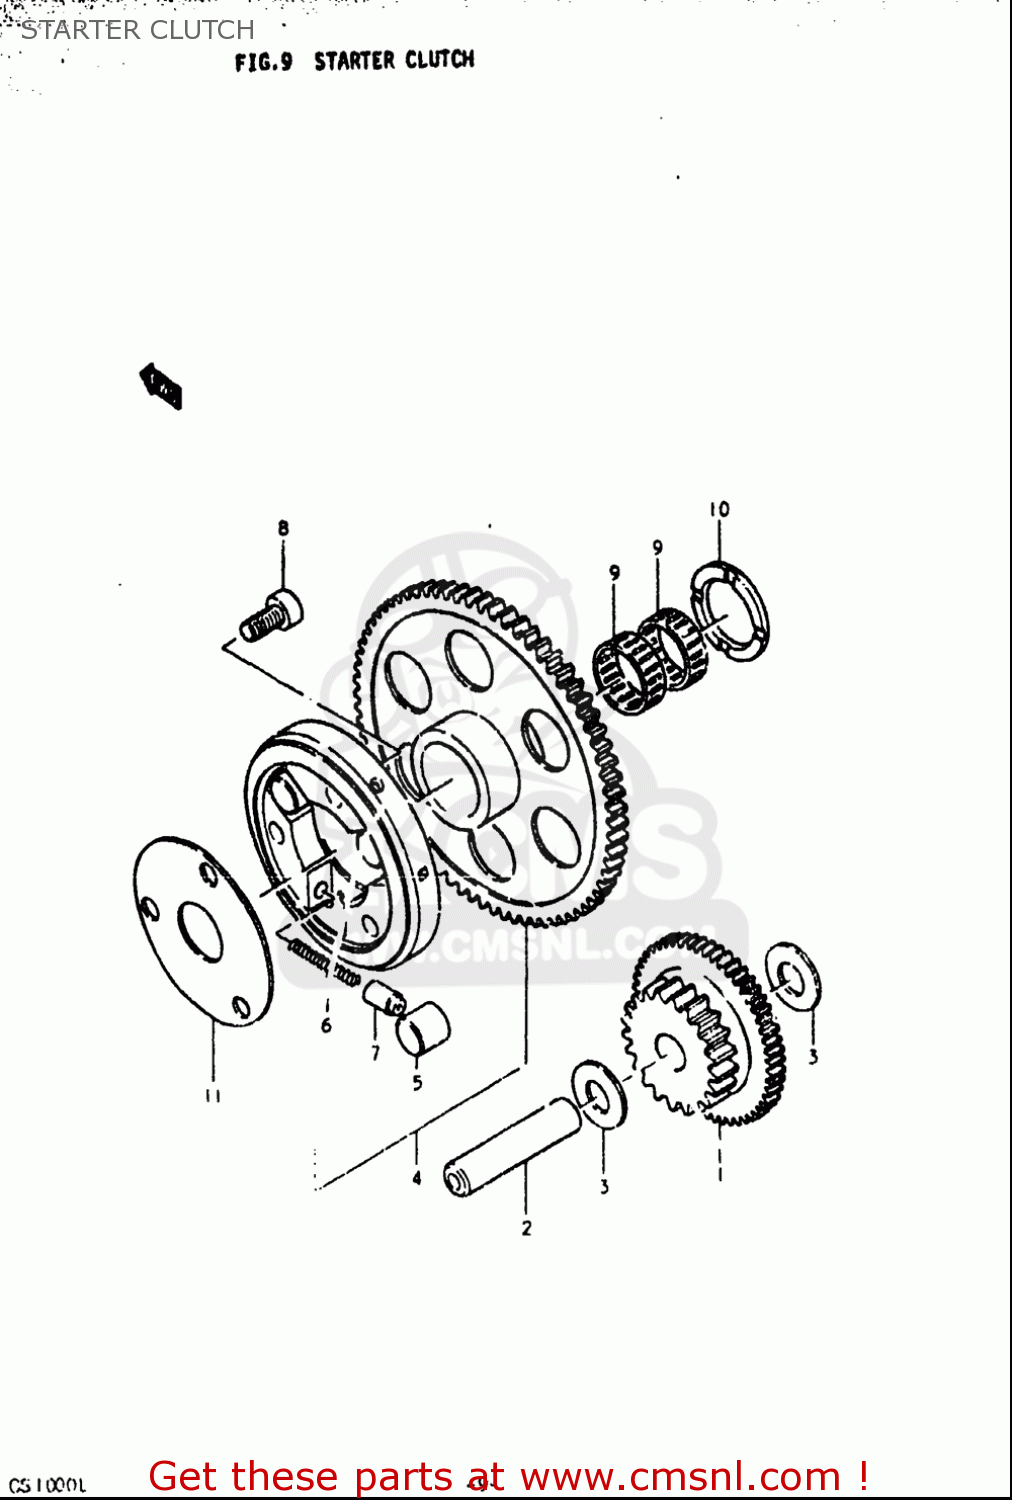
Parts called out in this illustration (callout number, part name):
2	PIN(7.4X13X56)
3	WASHER(13.3X25X0.85)
4	CLUTCH SET,STARTER
5	ROLLER(15X13)
6	SPRING
7	PIECE,PUSH
8	BOLT
9	BEARING(25X29X9.9)
10	WASHER(25X38X2.5)
11	SHIM,STARTER CLUTCH HUB
